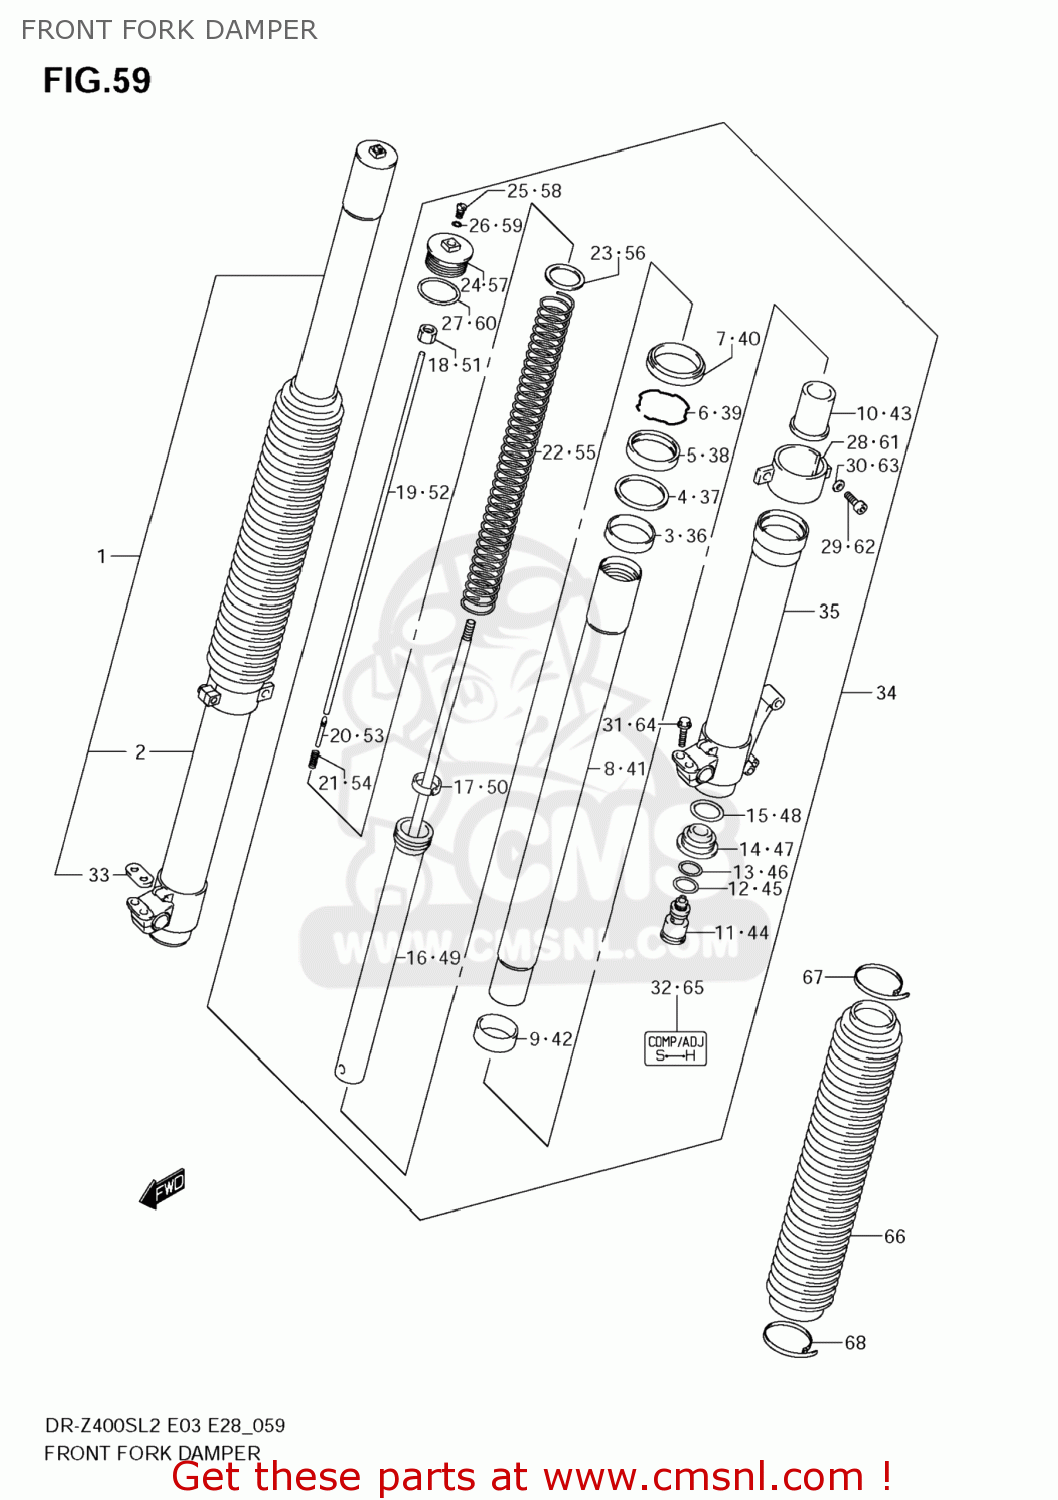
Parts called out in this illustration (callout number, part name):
1	DAMPER ASSY,FR FORK,R
2	TUBE,OUTER,R
3	BUSH,GUIDE
4	SPACER,SEAL
5	SEAL,OIL
6	RING,STOPPER
7	SEAL,DUST
8	TUBE,INNER
9	BUSH,SLIDE
10	PIECE,OIL LOCK
11	BOLT,CTR
12	O RING
13	O RING
14	PLATE,END
15	O RING
16	ROD,FR DAMPER
17	BUSH,SLIDE
18	NUT
19	ROD,PUSH
20	NEEDLE
21	SPRING,PUSH ROD
22	SPRING,FR(K=8.63N/0.88KG)
23	JOINT,SPRING
24	BOLT,FORK
25	BOLT,PLUG
26	O RING,PLUG
27	O RING
28	HOLDER,BOOT
29	BOLT
30	WASHER(5.5X10X1)
31	BOLT,HANDLE HOLDER(8X35)
32	LABEL
33	COVER,AXLE HOLDER
34	DAMPER ASSY,FR FORK,L
35	TUBE,OUTER,L
36	BUSH,GUIDE
37	SPACER,SEAL
38	SEAL,OIL
39	RING,STOPPER
40	SEAL,DUST
41	TUBE,INNER
42	BUSH,SLIDE
43	PIECE,OIL LOCK
44	BOLT,CTR
45	O RING
46	O RING
47	PLATE,END
48	O RING
49	ROD,FR DAMPER
50	BUSH,SLIDE
51	NUT
52	ROD,PUSH
53	NEEDLE
54	SPRING,PUSH ROD
55	SPRING,FR(K=8.63N/0.88KG)
56	JOINT,SPRING
57	BOLT,FORK
58	BOLT,PLUG
59	O RING,PLUG
60	O RING
61	HOLDER,BOOT
62	BOLT
63	WASHER(5.5X10X1)
64	BOLT,HANDLE HOLDER(8X35)
65	LABEL
66	BOOT
67	BAND,BOOT UPR
68	BAND,BOOT LWR
